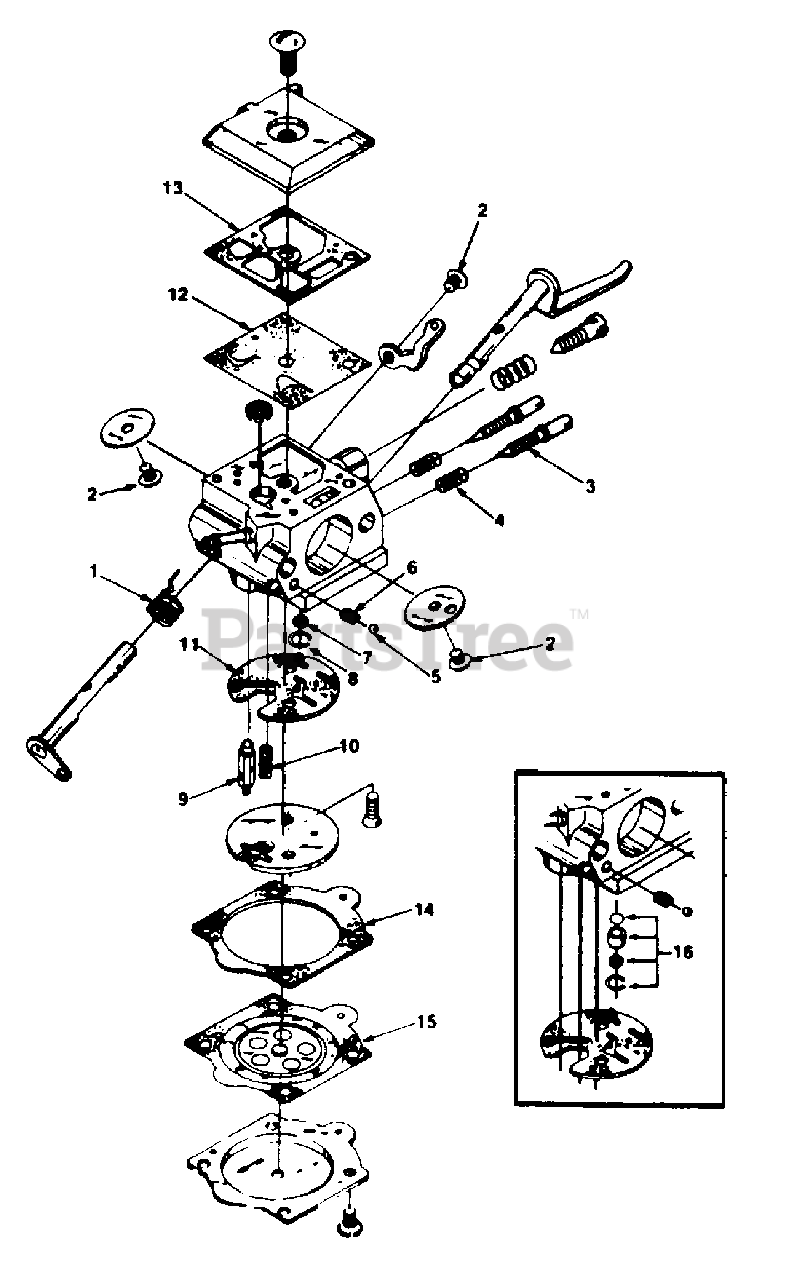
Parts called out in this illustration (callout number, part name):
1	Repair Kit
2	Repair Kit
3	Repair Kit
4	Repair Kit
5	Repair Kit
6	Repair Kit
7	Repair Kit
8	Repair Kit
9	Repair Kit
10	Repair Kit
11	Repair Kit
12	Repair Kit
13	Repair Kit
14	Repair Kit
15	Repair Kit
16	Check valve repair kit
